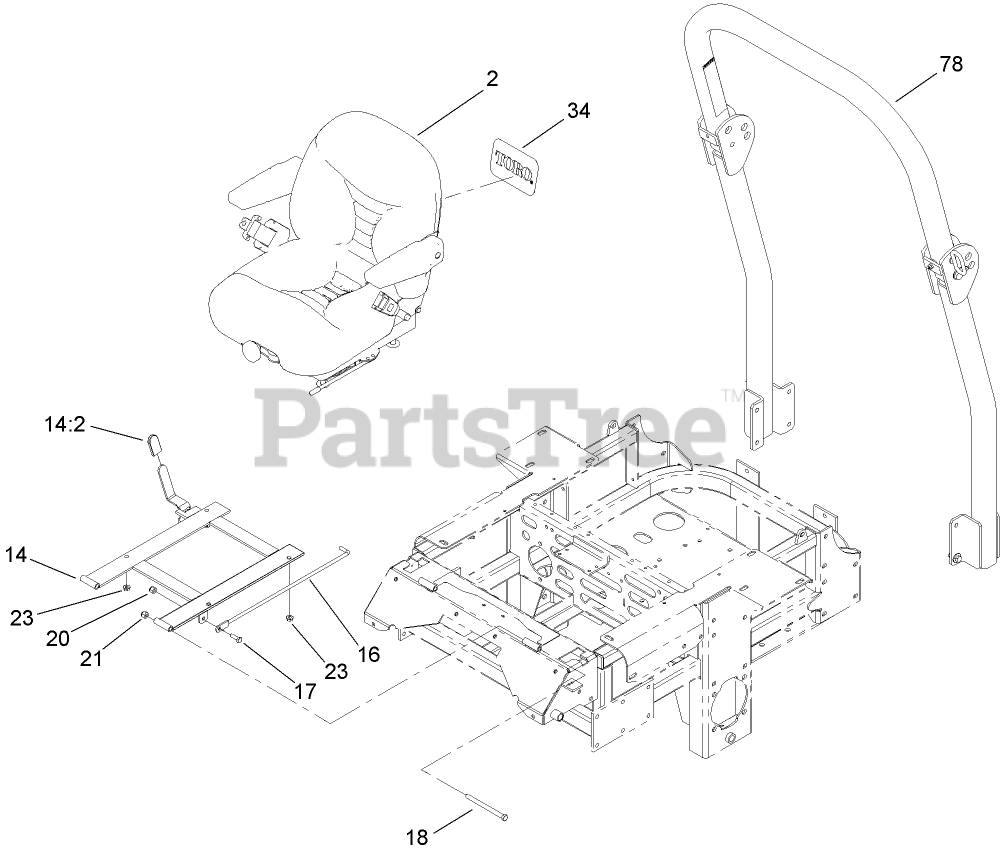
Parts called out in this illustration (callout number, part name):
2	DELUXE SEAT ASM
14	SEAT FRAME AND LATCH ASM
14:2	GRIP-LEVER
16	ROD-HOLDUP, SEAT
17	SCREW-HH
18	SCREW-HH
20	NUT-LOCK, NI
21	NUT-LOCK, NI
23	NUT-HF
34	DECAL
78	ROPS ASM
